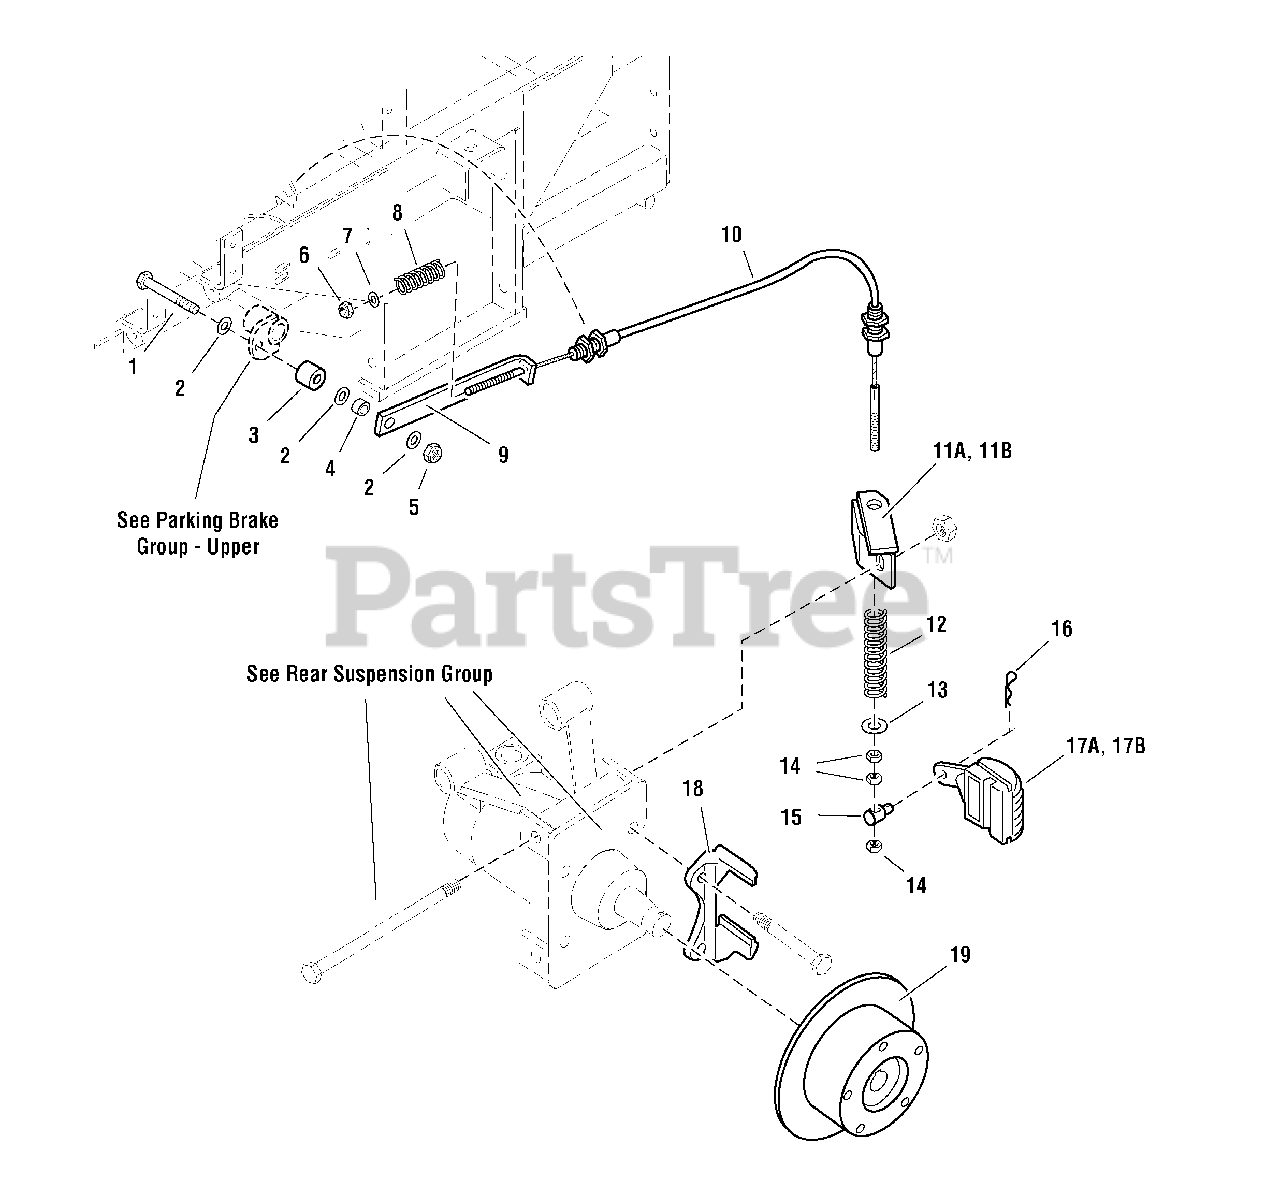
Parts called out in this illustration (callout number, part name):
1	CAPSCREW, Hex Hd, 3/8-16 x 2-1/4
2	WASHER, 3/8
3	SPACER, .39 x 1.00 x .88
4	SPACER, .38 x .50 x .27
5	NUT, Hex, Nylon Lock, 3/8-16
6	NUT, Hex, Nylon Lock, 5/16-24
7	WASHER, 5/16
8	SPRING, Compression
9	LINK, Brake Lock
10	CABLE, Brake
11A	BRACKET, Cable Mount-LH
12	SPRING, Compression
13	WASHER, Fender, 5/16
14	NUT, Hex, 5/16-24
15	ADJUSTER, Brake Linkage
16	HAIRPIN CLIP
17A	BRAKE CALIPER, LH
18	MOUNT, Brake Caliper
19	HUB, 8" Brake Disc
